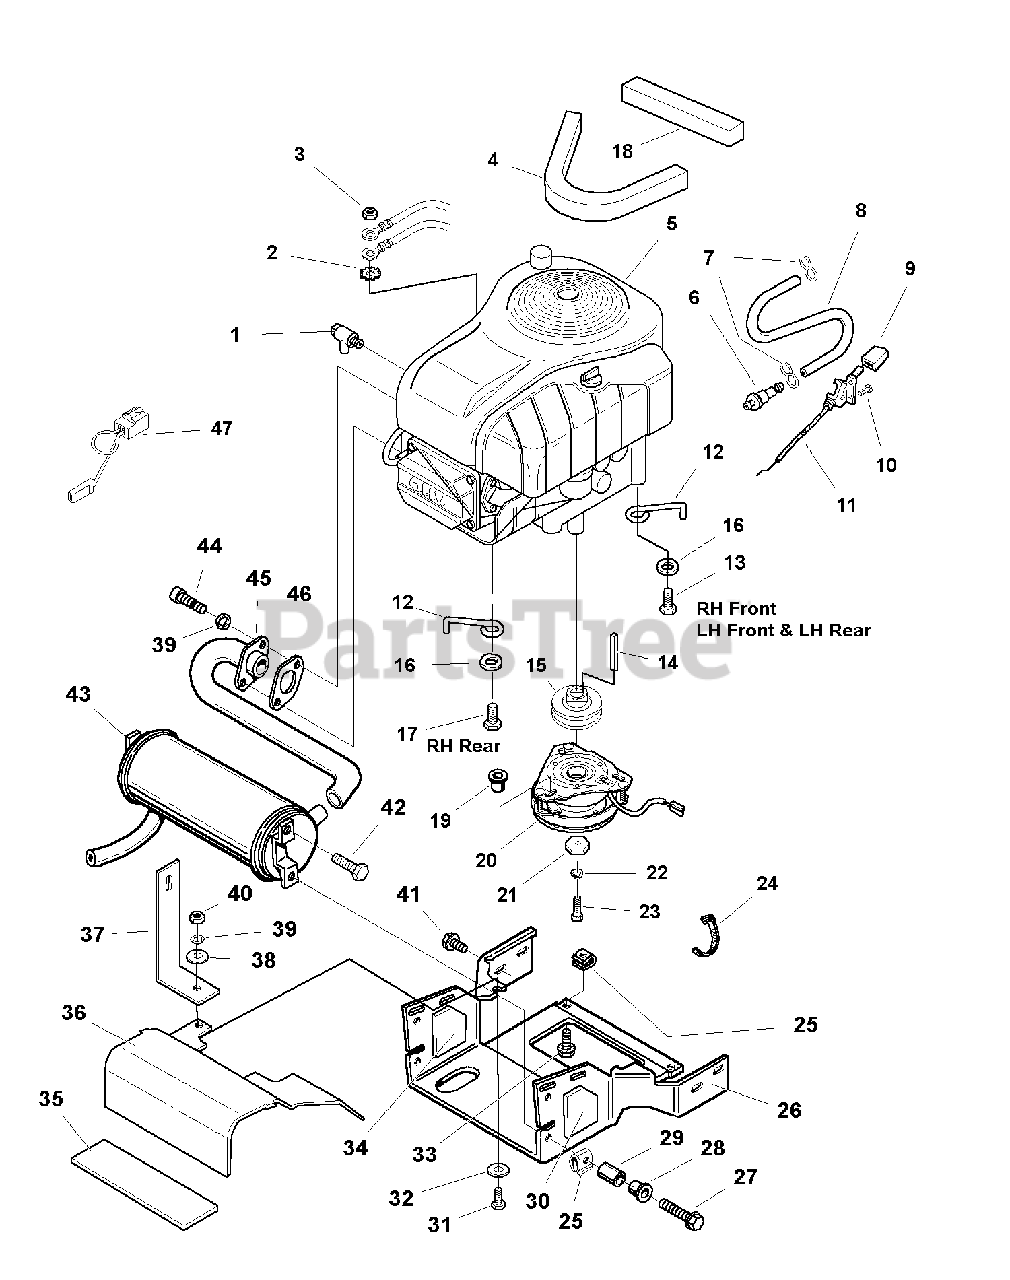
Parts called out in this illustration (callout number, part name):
1	VALVE, Shut Off
2	LOCKWASHER, External Tooth 3/8
3	NUT, Hex 3/8-16
4	SEAL, Foam
6	FUEL FILTER
8	HOSE, 12" Long
10	CAPSCREW, Hex 1/4-14 x 5/8
11	CONTROL, Throttle Cable
13	CAPSCREW, Hex Head Taptite, 3/8-16 x 1-1/2
15	PULLEY & HUB ASSEMBLY, Engine
16	WASHER
17	CAPSCREW, Hex Head Taptite, 3/8-16 x 2
19	SLEEVE, Clutch Anchor
20	CLUTCH, Electric, OGURA
21	WASHER, Hex, Special
22	LOCKWASHER, 7/16
23	CAPSCREW, Hex Head, 7/16-20 x 3
25	NUT, Speed 5/16-18
26	DUCT, Muffler, Lower
27	CAPSCREW, Hex Head Flange Lock, 5/16-18 x 1-1/4
30	INSULATION, LH (Export)
31	CAPSCREW, Hex Head, 5/16-18 x 1
32	WASHER, 5/16
33	CAPSCREW, Hex Head Flange Lock 5/16-18 x 3/4
34	INSULATION, RH (Export)
35	INSULATION, Foam, 6 x 11-3/8 (Export)
36	DUCT, Muffler Upper, Domestic
36	DUCT, Muffler Upper, Export
37	STRAP, Torque (Export)
38	WASHER, 5/16
39	LOCKWASHER, 5/16 (Export)
40	NUT, Hex 5/16-18 (Export)
41	CAPSCREW, Hex Head Taptite, 5/16-18 x 1/2
42	CAPSCREW, Hex Head Taptite,1/4-20 x 3/8
43	MUFFLER, Domestic
43	MUFFLER, Export
44	CAPSCREW, Hex Head, 5/16-18 x 3/4
45	PIPE, Exhaust
46	GASKET, Ehaust
47	WIRE ASSEMBLY, B&S, Domestic
47	WIRE ASSEMBLY, B&S, Export
